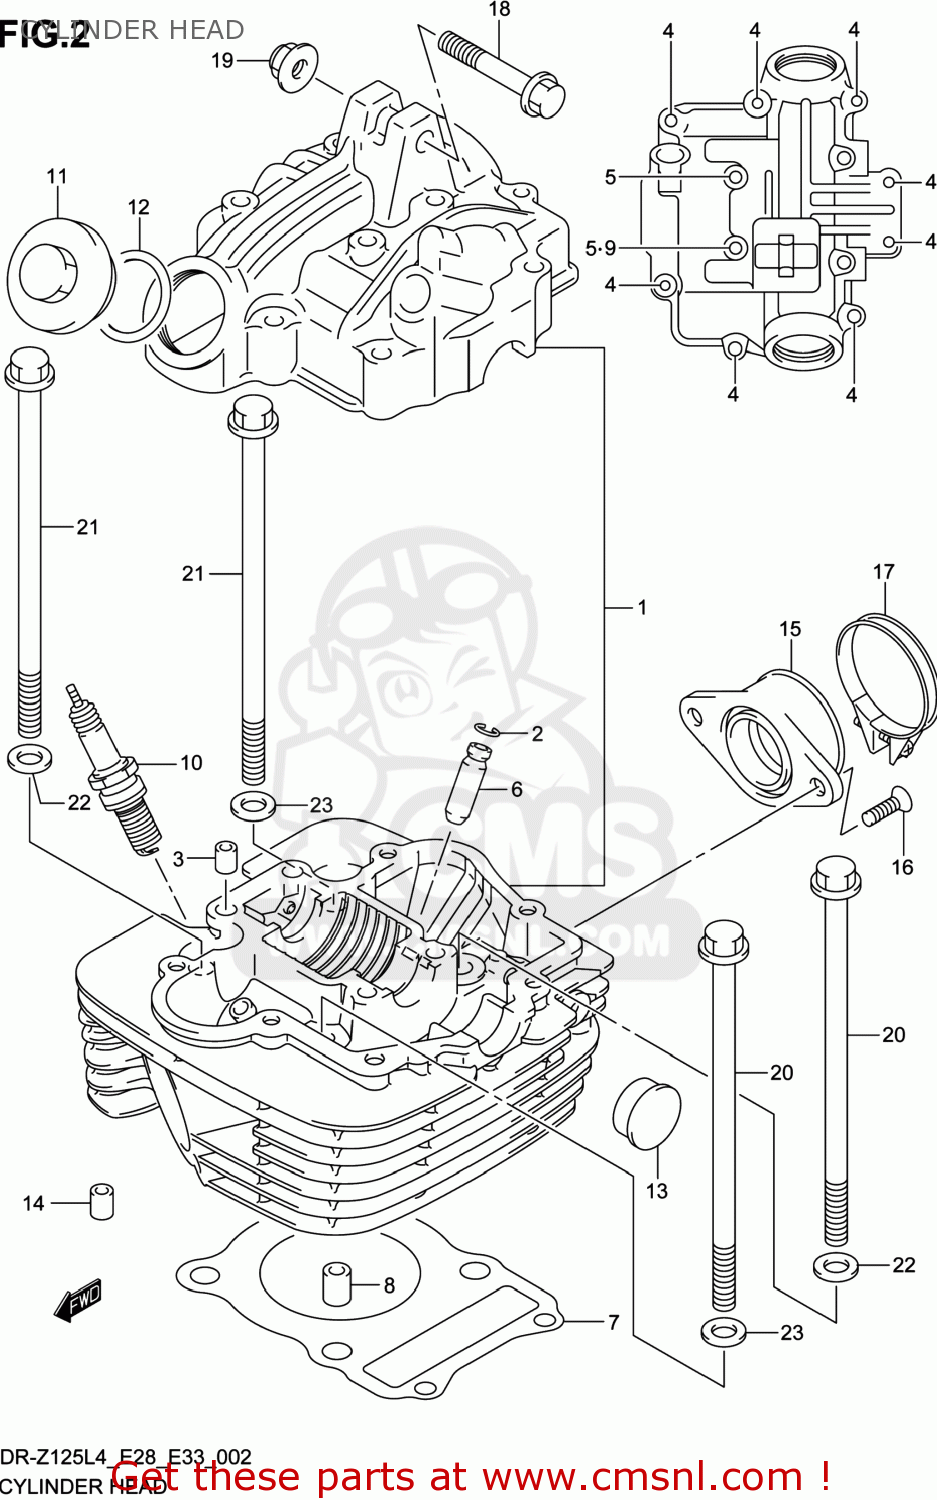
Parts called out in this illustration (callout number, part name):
1	HEAD ASSY,CYLINDER
2	RING,SNAP
3	PIN(6.2X8X11)
4	BOLT
5	BOLT
6	GUIDE,VALVE
7	GASKET.CYLINDER HEAD (NAS)
8	PIN
9	GASKET(5.8X13X1.2) (NAS)
10	PLUG,SPARK(DR8EA)
11	CAP,INSPECTION
12	O RING(D:3,ID:29.5)
13	PLUG(OD:22.5)
14	PAD,CYLINDER HEAD
15	PIPE ASSY,INTAKE
16	SCREW
17	CLAMP
18	BOLT(8X50)
19	NUT
20	BOLT(8X155)
21	BOLT(8X165)
22	WASHER(8.5X19X2.3)
23	GASKET(8.5X17X2.3) (NAS)
